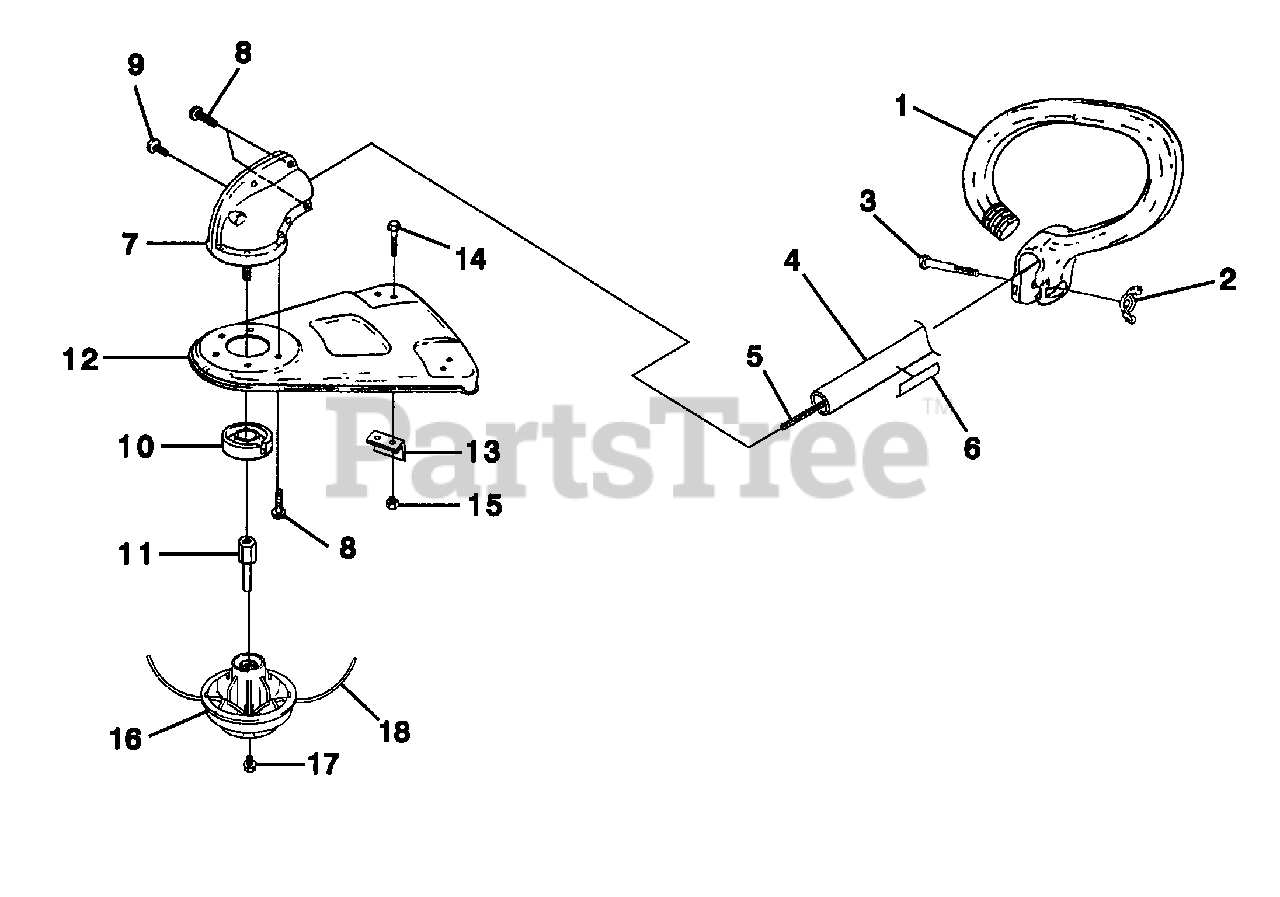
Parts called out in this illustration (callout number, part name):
1	HANDLE-Anti-Vibe
2	NUT-Wing, Washer Faced (1/4-20)
3	SCREW-Cap Hex Hd. (1/4-20 x 2")
4	DRIVESHAFT HOUSING ASSY.
5	SHAFT-Flexible
7	GEARHEAD
8	Screw, Taptite Hex Hd. (10-24 x 1/2")
9	Screw-Hex Hd. (10-24 x 5/8")
10	WASHER-Flanged
11	ADAPTER-Shaft
12	GRASS DEFLECTOR KIT
13	BLADE-Cut-off
14	SCREW-Mach.Hex Hd. (10-24 X 3/8")
15	NUT-Lock Hex (10-24)
16	STRINGHEAD-Pro-Cut w/line
17	SCREW-Stringhead Retainer
18	LINE-Replacement
